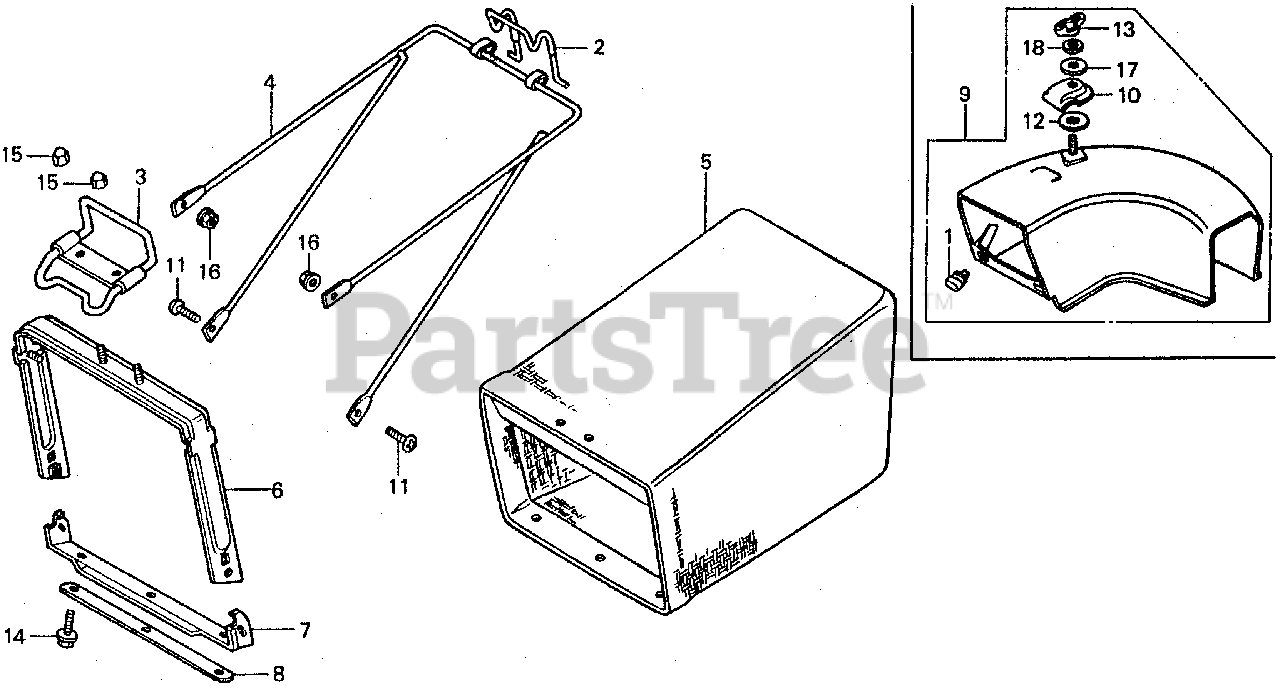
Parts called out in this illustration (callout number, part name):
1	STOPPER, DISCHARGE GUARD Use up to Frame SN 1186736.
2	GRIP, GRASS BAG (NOT AVAILABLE)
3	HANDLE, GRASS BAG
4	BAR, GRASS BAG
5	FABRIC, GRASS BAG
6	FRAME A, BAG
7	FRAME B, BAG
8	PLATE, BAG
9	ADAPTER, DISCHARGE (N/A: SEE COMPONENTS)
10	PLATE, CLAMP
11	SCREW, TORUS (6X16)
12	WASHER, TANK SETTING
13	WINGNUT, TOOL BOX SETTING
14	BOLT-WASHER (6X12)
15	NUT, CAP (6MM)
16	NUT, FLANGE (6MM)
17	WASHER, PLAIN (6MM)
18	WASHER, SPRING (6MM)
